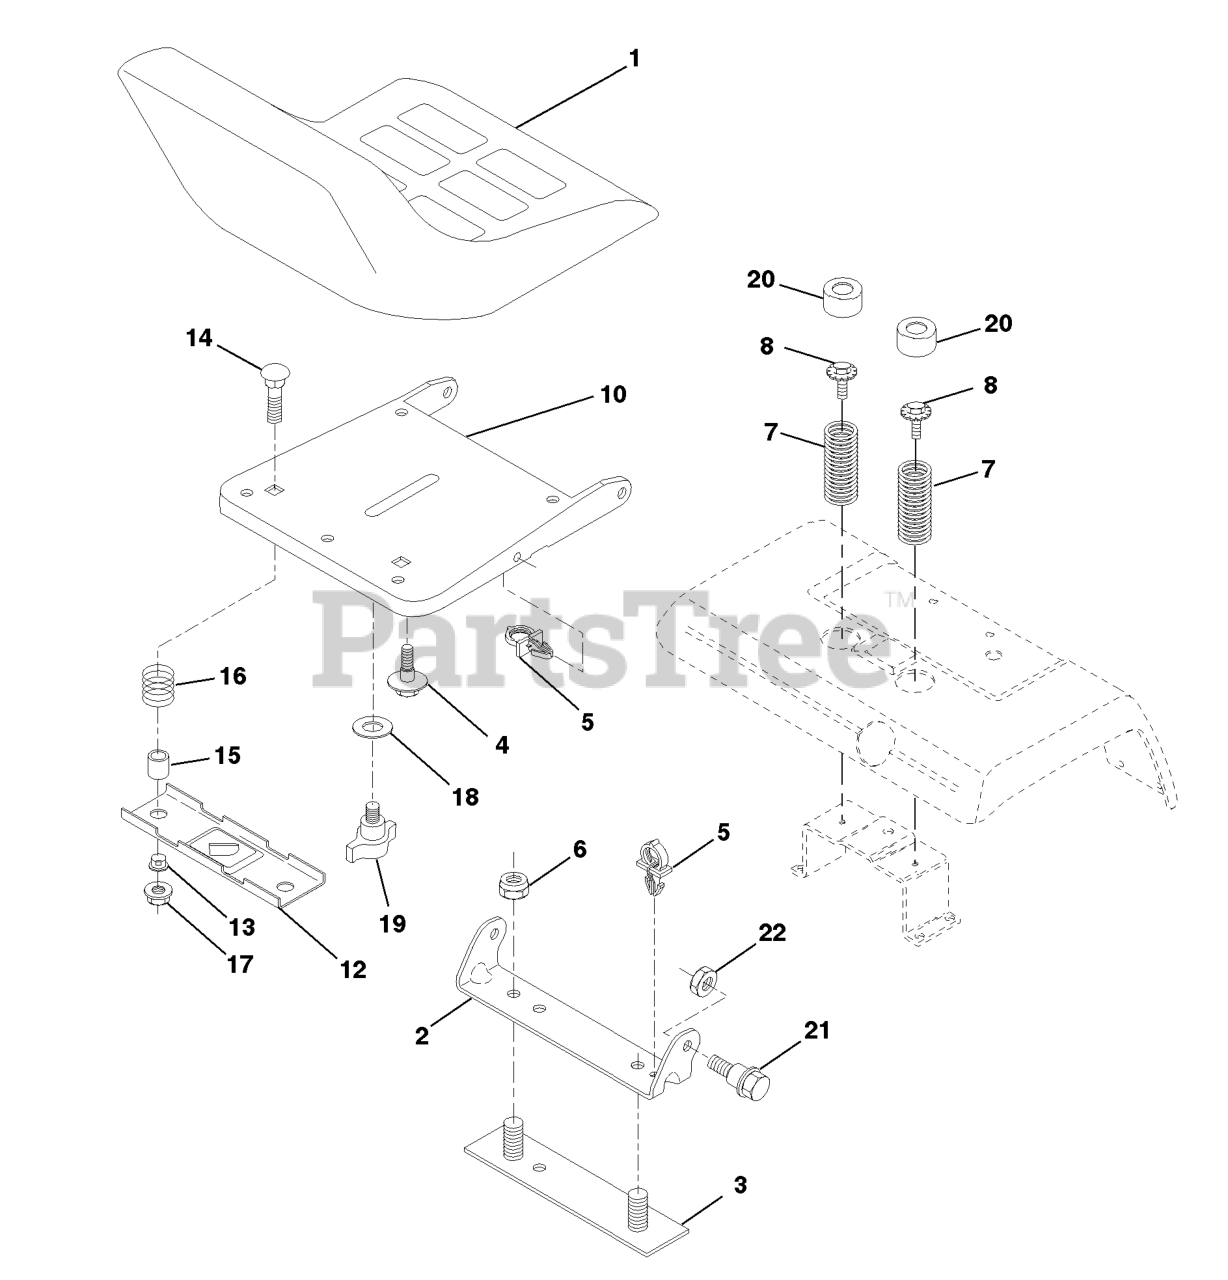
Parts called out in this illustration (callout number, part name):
1	SEAT
2	SEAT PIVOT BRKT
3	STRAP
4	BOLT,SHOULD
6	NUT
7	SPRING COMPRESSION
8	BOLT HEX WASHER HD 5/16-18
10	PAN, SEAT
12	BRKT SWITCH
14	BOLT.ROUND.HEAD.SQUARE.NECK
15	SPACER SPLIT
16	SPRING COMPRESSED
17	NUT T
19	KNOB 1/2" YT
20	CAP SPRING
21	BOLT SHOULDER 5/16-18
22	LOCKNUT
